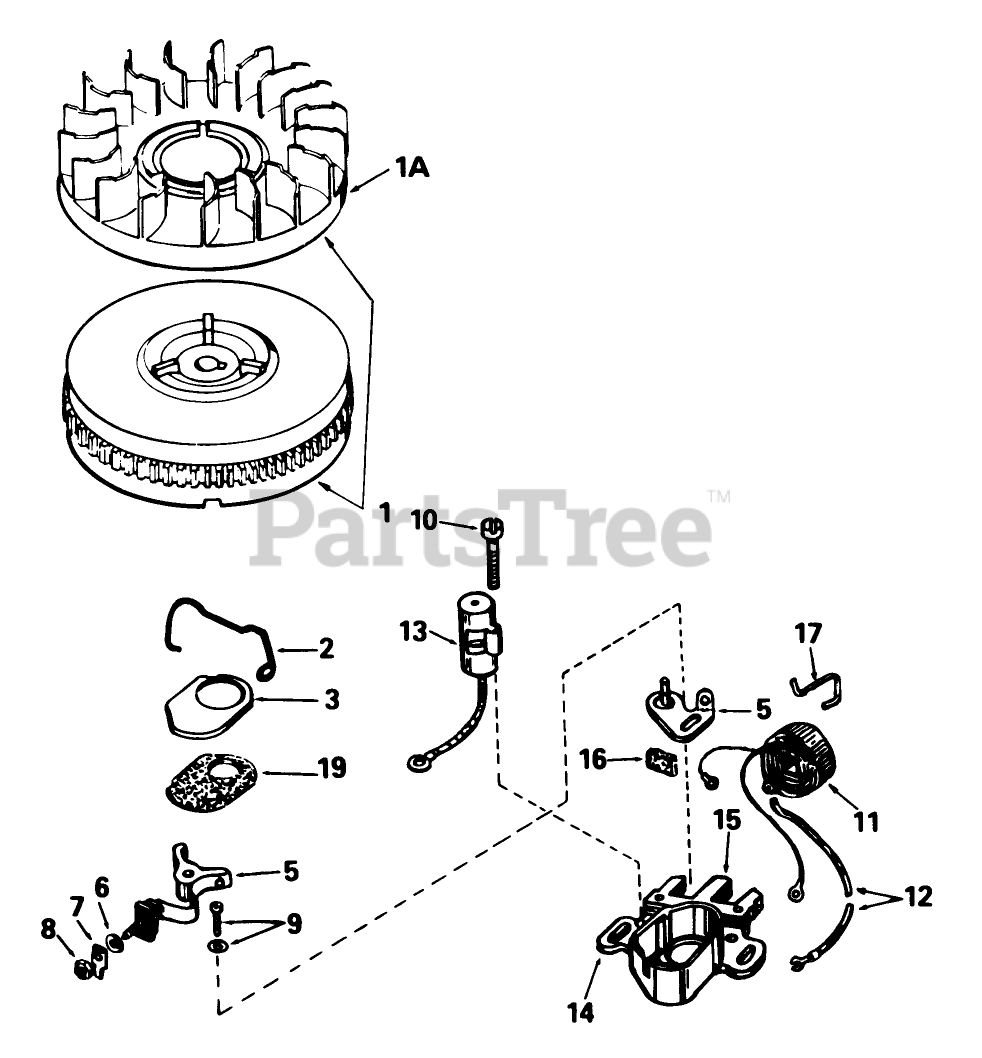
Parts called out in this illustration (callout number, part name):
1	Flywheel (Incl. Ref. #1A)
1A	Fan
2	Spring Breaker Box
3	Cover-Dust
5	Breaker Assy.
6	Washer
7	Terminal, Ground
8	DECAL
9	Breaker Screw
10	Condenser Screw
11	Coil Assy. (Incl. No. 12)
12	Wire, Lead
13	Condenser
14	Core Plate
15	Stator Assy. (Incl. Ref. #2 thru 11, 13, 14, 16, 17 19)
16	Felt,Cam Wiper
17	Clip, Coil
19	Gasket, Dust Cover
